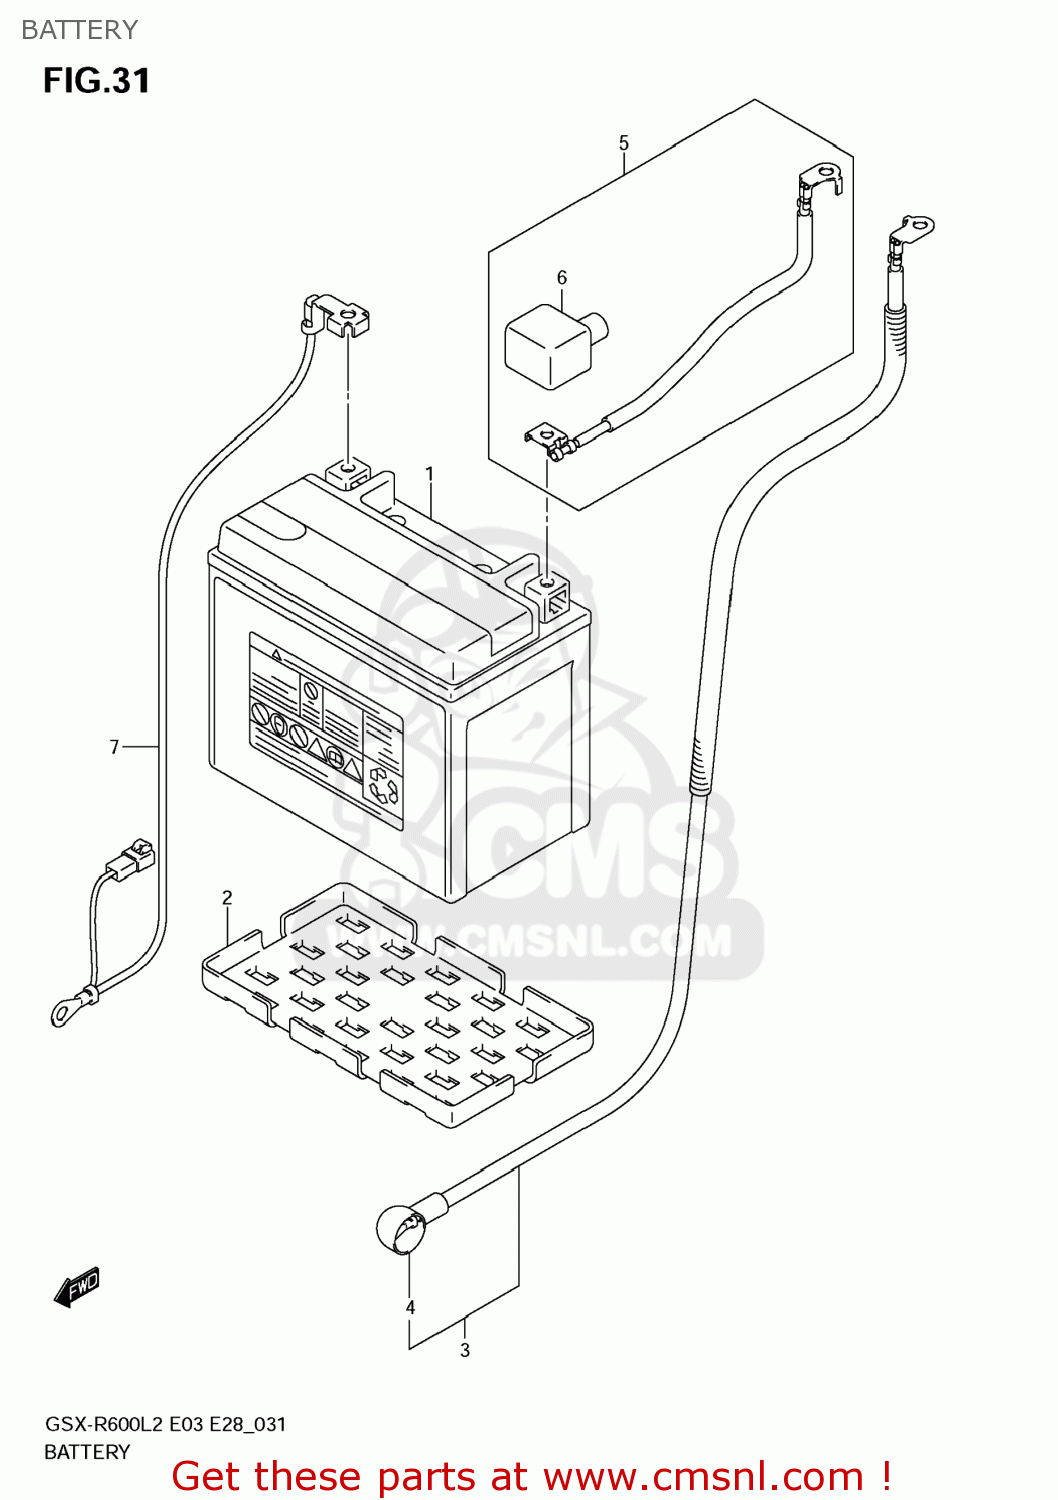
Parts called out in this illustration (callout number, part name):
1	BATTERY ASSEMBLY (12V) FTX
2	PROTECTOR,BATTERY
3	WIRE,STARTER MOTOR LEAD
4	CAP,STARTER MOTOR
5	WIRE,BATTERY PLUS LEAD
6	CAP,BATTERY PLUS
7	WIRE,BATTERY MINUS LEAD
